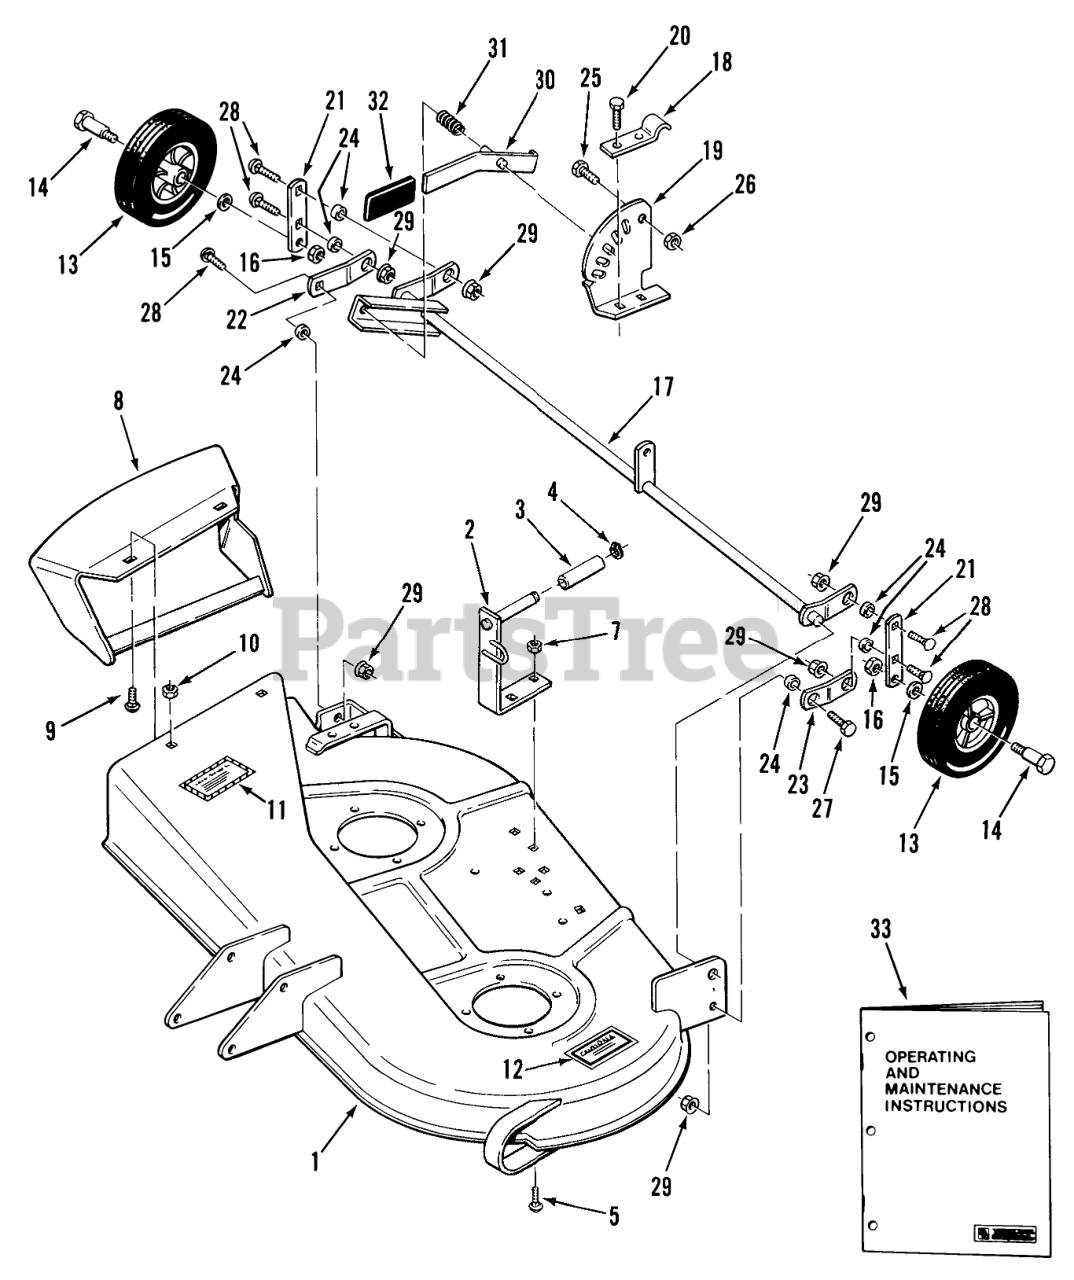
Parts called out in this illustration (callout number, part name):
1	Mower Deck
2	ASSY-BRACKET GUID R
3	SPACER
4	Snap Ring
5	Bolt-Carriage
7	Nut
8	ASSY-CHUTE EXT R
9	CARRIAGE BOLT -4
10	Nut
11	DECAL
12	Caution Decal
13	WHEEL-GAUGE
15	WASHER
16	Nut
17	Gage Wheel Support
18	Pivot Bracket
19	Quadrant
20	Bolt
21	LINK R
22	ARM-PIVOT RH R
23	Arm LH
24	SPACER
26	Nut
27	BOLT
28	Bolt
29	LOCKNUT-FLANGE
30	Lever
31	SPRING-COMPRESSION
33	Operating and Maintenance Instructions
